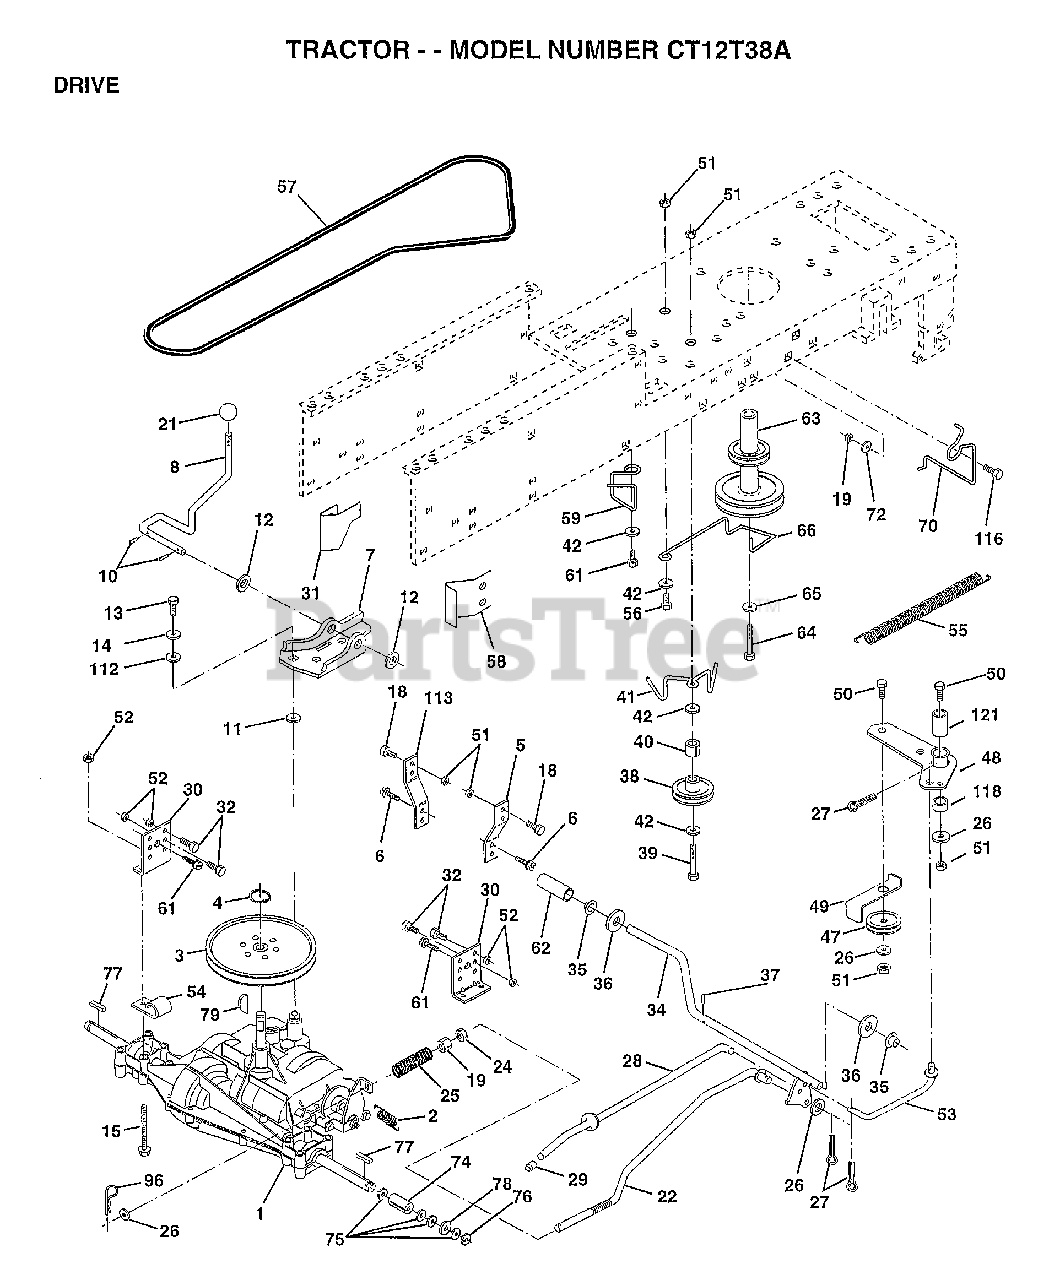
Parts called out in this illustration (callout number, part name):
1	TRANSAXLE PEERLESS
2	SPRING.BRAKE.RETU
3	PULLEY TRANS
5	STRAP TORQUE
6	SCREW
8	SHIFT ROD
10	PIN COTTER 1/8
11	WASH-SHFT PLT LT
12	WASHER
13	BOLT.1/4-28.W/PAT
14	LOCKWASHER
15	BOLT.HX.FLG.5/16
18	BOLT
19	NUT
21	KNOB T (1/2-HOLE)
22	BRAKE ROD
24	NUT
25	SPRING ROD LT
26	WASHER
27	COTTER PIN
28	ROD.BRAKE.PARK.LT
29	PLUNGER CAP T
30	TRANSAXLE MTG BKT
31	"KEEPER,BELT LH T"
32	BOLT
34	SHAFT ASM-PEDAL F
35	NYLON BEARING
36	WASHER LT
38	PULLEY.IDLER.FLAT
39	BOLT
40	SPACER T
42	WASHER
48	BELLCRANK ASM
49	RETAIN BELT
53	"LINK, CLUTCH T"
54	CLIP T
55	"SPRING, RETURN LT"
58	"KEEPER,BELT RH T"
59	KEEPER BELT CNTSP
61	SCREW
62	PEDAL COVER T
63	PULLEY.ENGINE
64	BOLT
65	LOCKWASHER
66	KEEPER-BELT
70	KEEPER BELT ENG
72	WASHER
74	SPACER AXLE
75	WASHER
76	E-RING LT
77	SQUARE KEY
78	WASHER
96	RETAINER M
112	WASHER LT
113	"STRAP,TORQUE"
116	BOLT RDHD 3/8-16
118	SPACER-BELLCRANK
121	NYLINER-CLUTCHING
